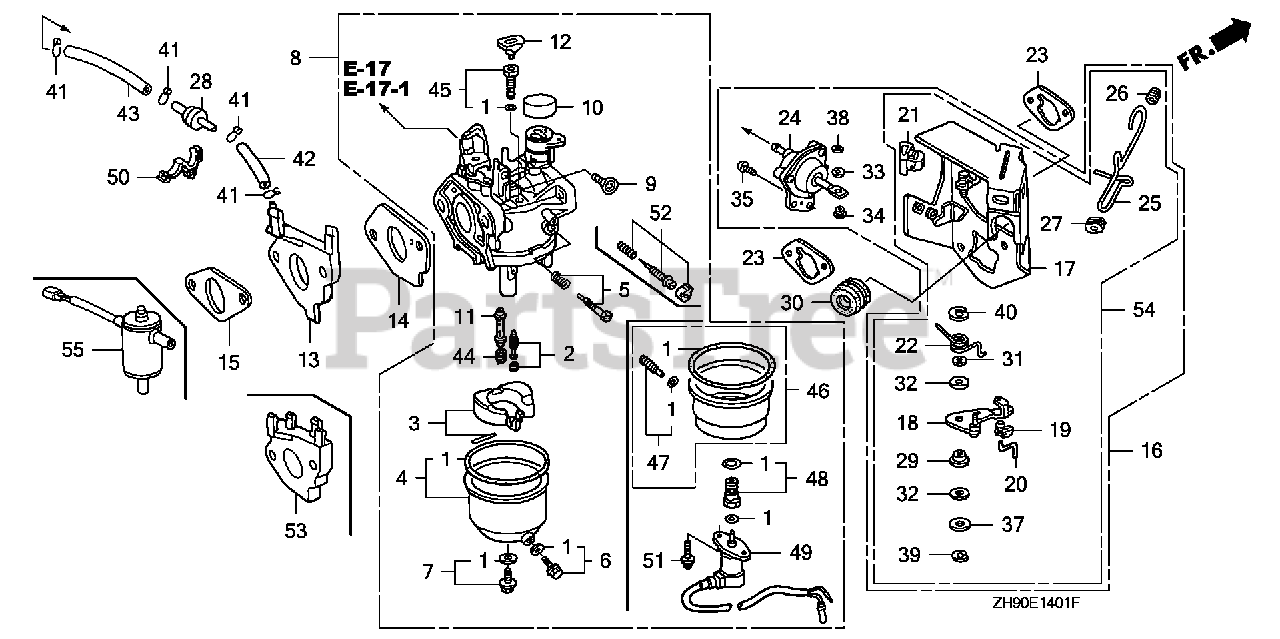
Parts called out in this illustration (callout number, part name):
1	GASKET SET
2	VALVE SET, FLOAT
3	FLOAT SET
8	CARBURETOR ASSY. (BE77Q A) (N/A: USE ALTERNATE P/N 16100-ZH9-D41)
9	SCREW, THROTTLE STOP
10	CAP, CHOKE LEVER DUST
11	NOZZLE, MAIN (CARBURETOR NO.)
12	COLLAR, SET
14	GASKET, CARBURETOR
15	GASKET, INSULATOR
17	STAY, SOLENOID
18	LEVER, CHOKE
19	JOINT, ROD
20	ROD, CHOKE
21	STOPPER, CHOKE ROD
22	SPRING, MANUAL CHOKE
23	GASKET, AIR CLEANER
25	ROD, CHOKE CONTROL
26	GROMMET, CHOKE ROD
27	GUIDE, CHOKE ROD
29	BUSH, ARM PIVOT
30	GROMMET, FENDER
31	WASHER, CHOKE LEVER
32	SEAL, CHOKE LEVER
37	WASHER, PLAIN (5MM)
39	E-RING (4MM)
40	E-RING (7MM)
44	JET, MAIN (#85) Use up to Engine SN BE81B B.
44	JET, MAIN (#88) Use up to Engine SN BE81B B.
44	JET, MAIN (#90) Use from Engine SN BE81B C.
45	JET SET, PILOT (#40) (ADVENTURE GREEN) (CARBURETOR NO.)
46	CHAMBER SET, FLOAT
47	SCREW SET, DRAIN (ADVENTURE GREEN) (CARBURETOR NO.)
48	SCREW SET B
49	VALVE ASSY., SOLENOID
51	SCREW-WASHER (5X12)
52	SCREW SET
53	INSULATOR, CARBURETOR
54	STAY ASSY., MANUAL CHOKE
